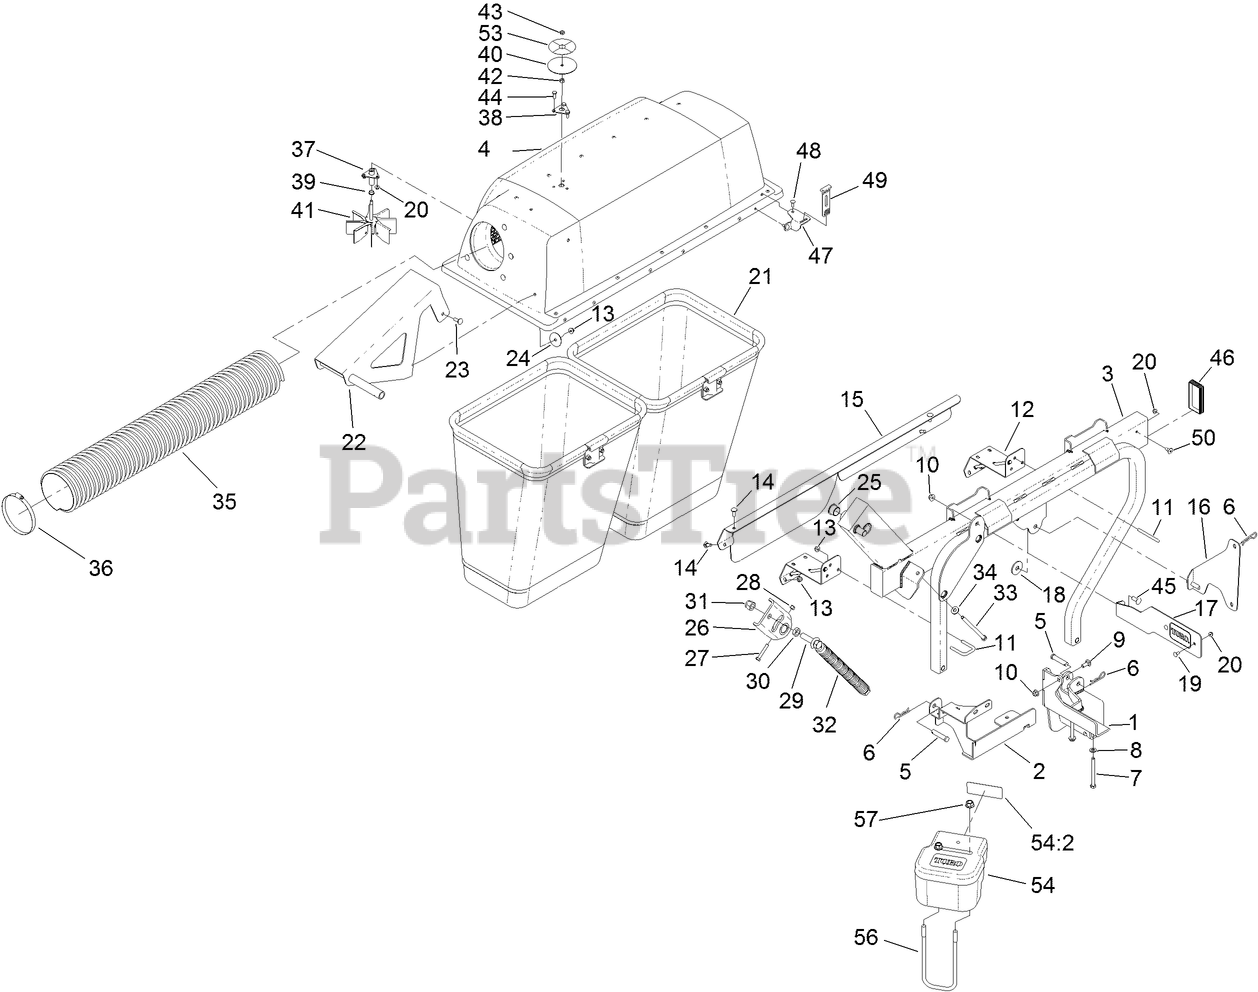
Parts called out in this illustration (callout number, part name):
1	MOUNT-BAGGER
2	BRACKET-EXTENSION, TUBE
3	FRAME-BAGGER
4	HOOD ASM
5	PIN-CLEVIS
6	PIN-COTTER
7	SCREW-HH
8	WASHER-FLAT
9	BOLT-CARR
10	NUT-HF, NI
11	U-BOLT-SQUARE
12	COVER, WHEEL
13	NUT-HF, NI
14	BOLT-CARR
15	COVER-WHEEL
16	MOUNT-SUPPORT, BAGGER
17	BRACKET-MOUNT, BAGGER W/DECAL
18	WASHER-THRUST
19	SCREW-CARR
20	NUT-HF
21	BAG AND FRAME ASM
22	PIVOT-HOOD
23	BOLT-CARR
24	WASHER
25	BUSHING
26	BELLCRANK ASM
27	SCREW-HH
28	NUT-LOCK, NI
29	SCREW-HH
30	NUT-JAM
31	NUT-LOCK, NI
32	SPRING-EXTENSION
33	BOLT-TAP, HH
34	WASHER-BELLEVILLE
35	HOSE-FLEXIBLE
36	CLAMP-HOSE, 5.5 Inch
37	MOUNT-FILL INDICATOR
38	PLATE-FILL INDICATOR
39	BUSHING-FLANGED
40	PLATE-FILL INDICATOR
41	BAG FILL FAN ASM
42	NUT-HEX, SIDE DEFORM
43	NUT-JAM
44	SCREW-HH
45	SCREW-CARR
46	CAP-END
47	BRACKET-STRAP
48	BOLT-CARR
49	STRAP-HOLD DOWN
53	DECAL-ROTATION INDICATOR
54	Weight ASM
54:2	DECAL-WARNING, COUNTERWEIGHT
56	U-BOLT
57	NUT-LOCK
